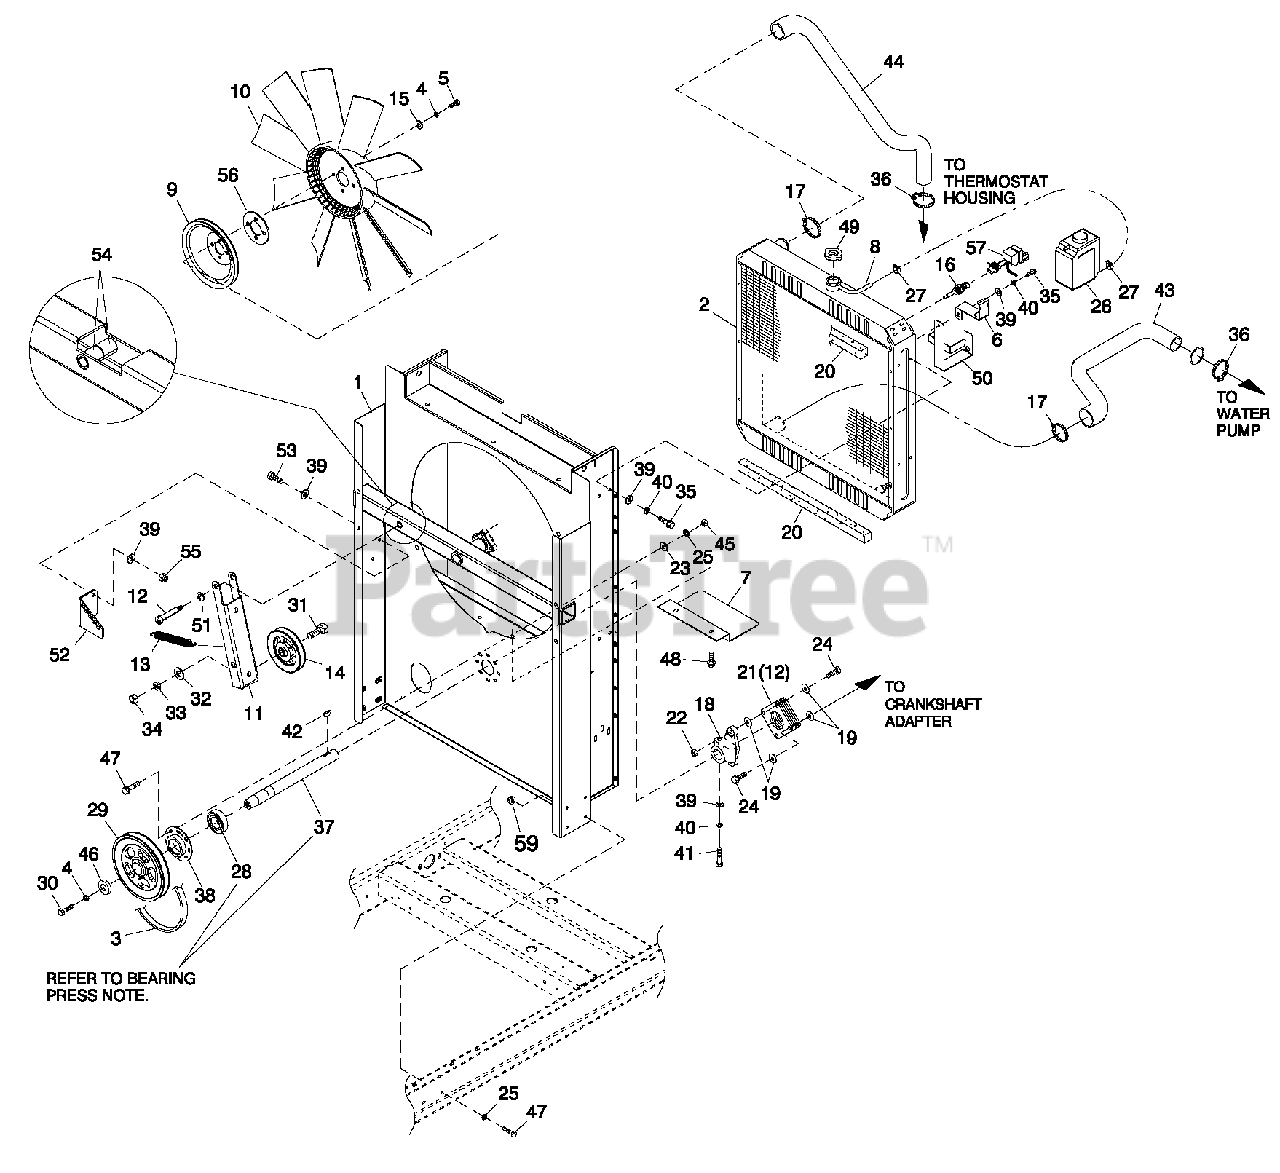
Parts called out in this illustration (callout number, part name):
1	WELDMENT RADIATOR SUPPORT C2
2	RADIATOR 598 X 568 X 49 CPL RH
3	V-BELT 31/64" X 57-3/8"
4	WASHER LOCK M10
5	SCREW HHC M10-1.5X 30 G10.9
6	BRACKET, SIGNAL CONDITIONER (USED ONLY
7	SHIELD RADIATOR C4
8	HOSE 9/32 ID (27" LG)
9	PULLEY FAN V-GROOVE 9"
10	FAN COOL 22" D IA 10 BLADE LH
11	ARM BELTTENSIONER
12	SHOULDER BOLT 1/2 X 2-1/4"
13	SPRING TENSION CPL
14	PULLEY V-BELT 4" FLANGED
15	WASHER FLAT 3/8-M10 ZINC
16	PROBE, COOLANT LEVEL 3/8NPTF
17	CLAMP HOSE #28 1.32-2.25
18	HUB FLEX PLATE
19	WASHER FLEX (THIN)
20	TAPE FOAM 1 X 1 (26.75" LG)
21	DISK FLEX
22	NUT HEX LOCK 5/16-24 NY INS
23	WASHER FLAT 1/4-M6 ZINC
24	SCREW HHC 5/16-24X1.124
25	WASHER LOCK M6-1/4
26	TANK COOLANT RECOVERY
27	CLAMP HOSE BAND 1/4
28	BEARING #6205 2NSE C3 E SRI2 S
29	PULLEY 4.5" DIA MACHINED
30	SCREW HHC M10-1.5X30 G8.8
31	SCREW HHC 1/2-13X 2" G8
32	WASHER FLAT 1/2 ZINC
33	WASHER LOCK 1/2
34	NUT HEX 1/2-13 STEEL
35	SCREW HHFC M8-1.25 X 20 W/M6
36	CLAMP HOSE #24 B1.06-2.00
37	SHAFT FAN DRIVE
38	RETAINER BEARING
39	WASHER FLAT 5/16-M8 ZINC
40	WASHER LOCK M8-5/16
41	SCREW HHC M8-1.25X 45 C8.8
42	KEY WOODRUFF 4X 19D
43	HOSE LOWER RADIATOR G2
44	HOSE UPPER RADIATOR G2 (USED WITH MANFLD P/N 0G0707)
45	NUT HEX M6X1.0G8YELCHR
46	SPACER .5 X 1.5 X .25 STL/ZINC
47	SCREW HHFC M6-1.0X 20 G8.8
48	SCREW THF M6-1 X 16 N WA Z/JS
49	CAP RADIATOR 13 PSI
50	BRACKET COOLANT TANK
51	WASHER NYLON .50 X .87 X .06
52	BRACKET TENSIONER SPRING
53	SCREW HHC M8-1.25X20 C8.8
54	BEARING SLEEVE 1/2/X 3/4X 1
55	NUT HEX LOCK M8-1.25 NY INS
56	SPACER CPL COOLING FAN 1/8"
57	ASSY PCB LCL SENSOR (USE WITH I/N 16, P/N
59	NUT FLANGE M6-1.0 NYLOK
